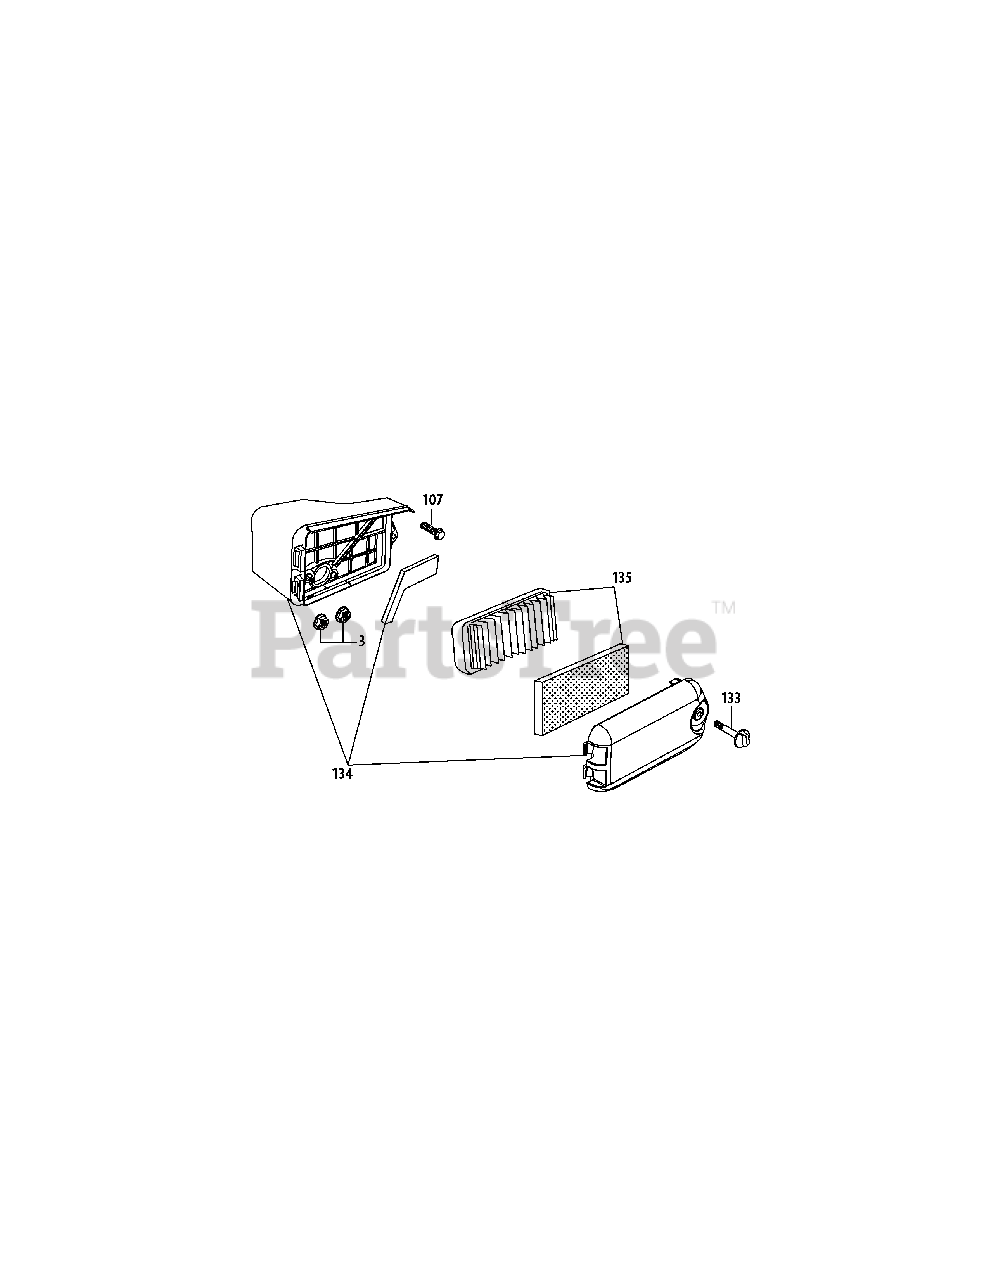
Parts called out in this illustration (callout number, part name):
3	Nut M6 X 10 Mm
107	Bolt M6×35
133	Air Filter Cover Thumb Screw
134	Air Cleaner Housing Assy Comp
135	Air Cleaner Kit
